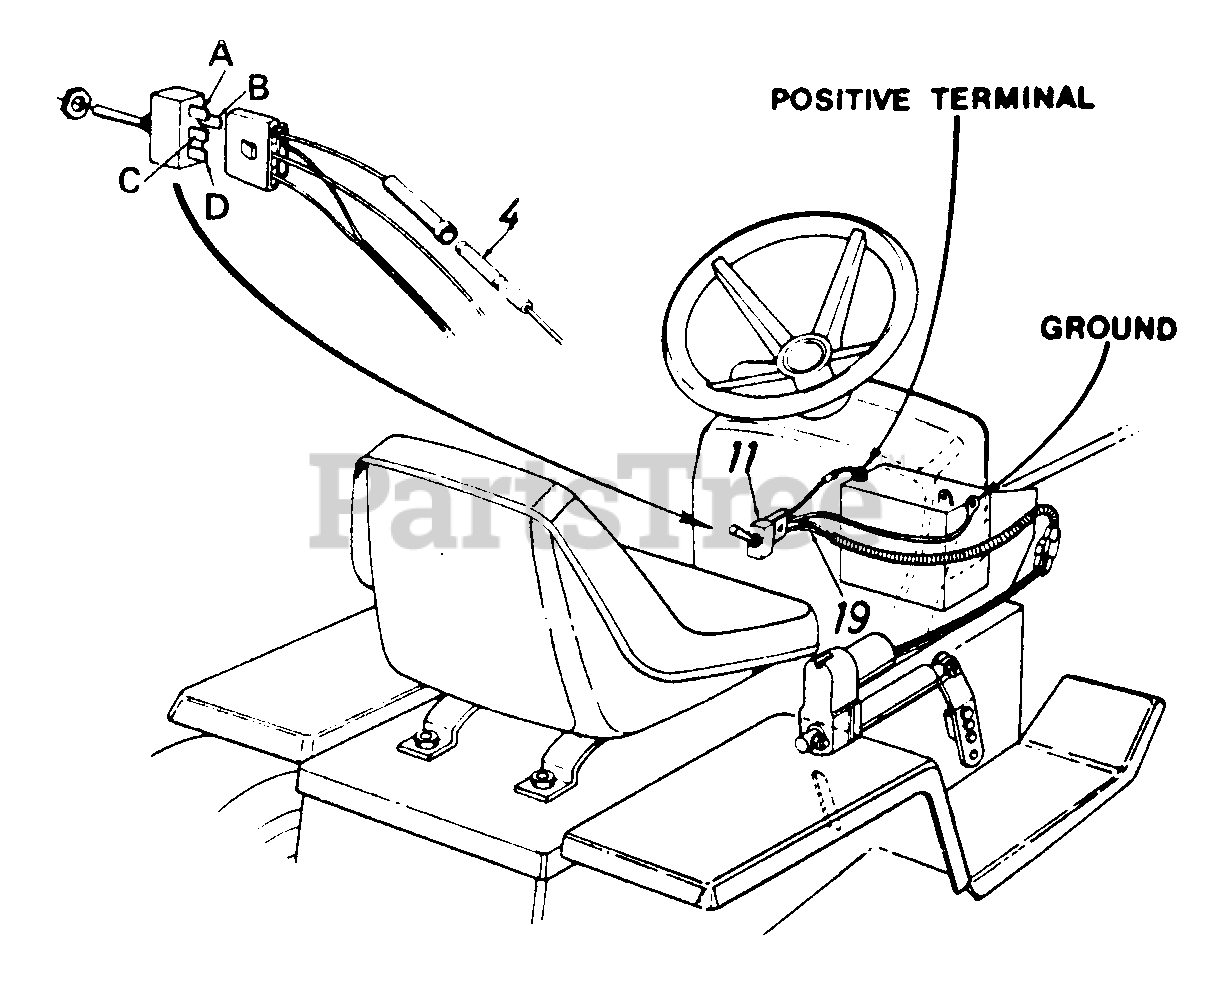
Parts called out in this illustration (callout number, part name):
4	Fuse 30 AMP
11	Toggle Switch
19	Wire Harness
A	Connects to Positive Terminal on Battery
B	Connects to Actuator
C	Ground Wire-to Frame
D	Connects to Actuator
